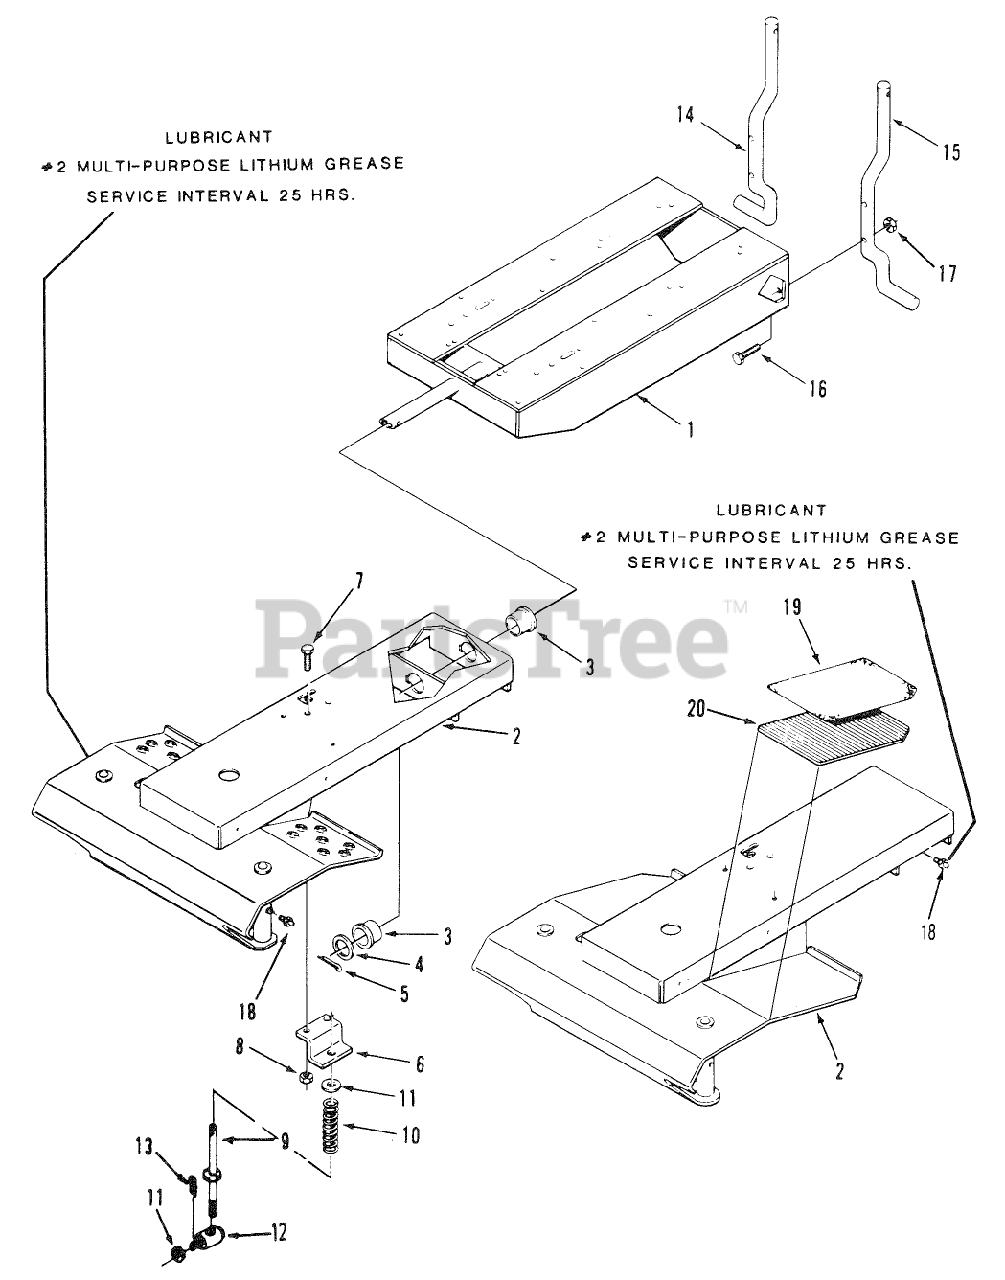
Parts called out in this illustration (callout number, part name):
1	ASS'Y-FRAME REAR *R
9	ASSY ROD
10	SPRING-COMPRESSION
11	Washer 3/8 SAE
14	REAR ROD RH *B
15	REAR ROD LH *B
20	PAD FOOTREST RH
